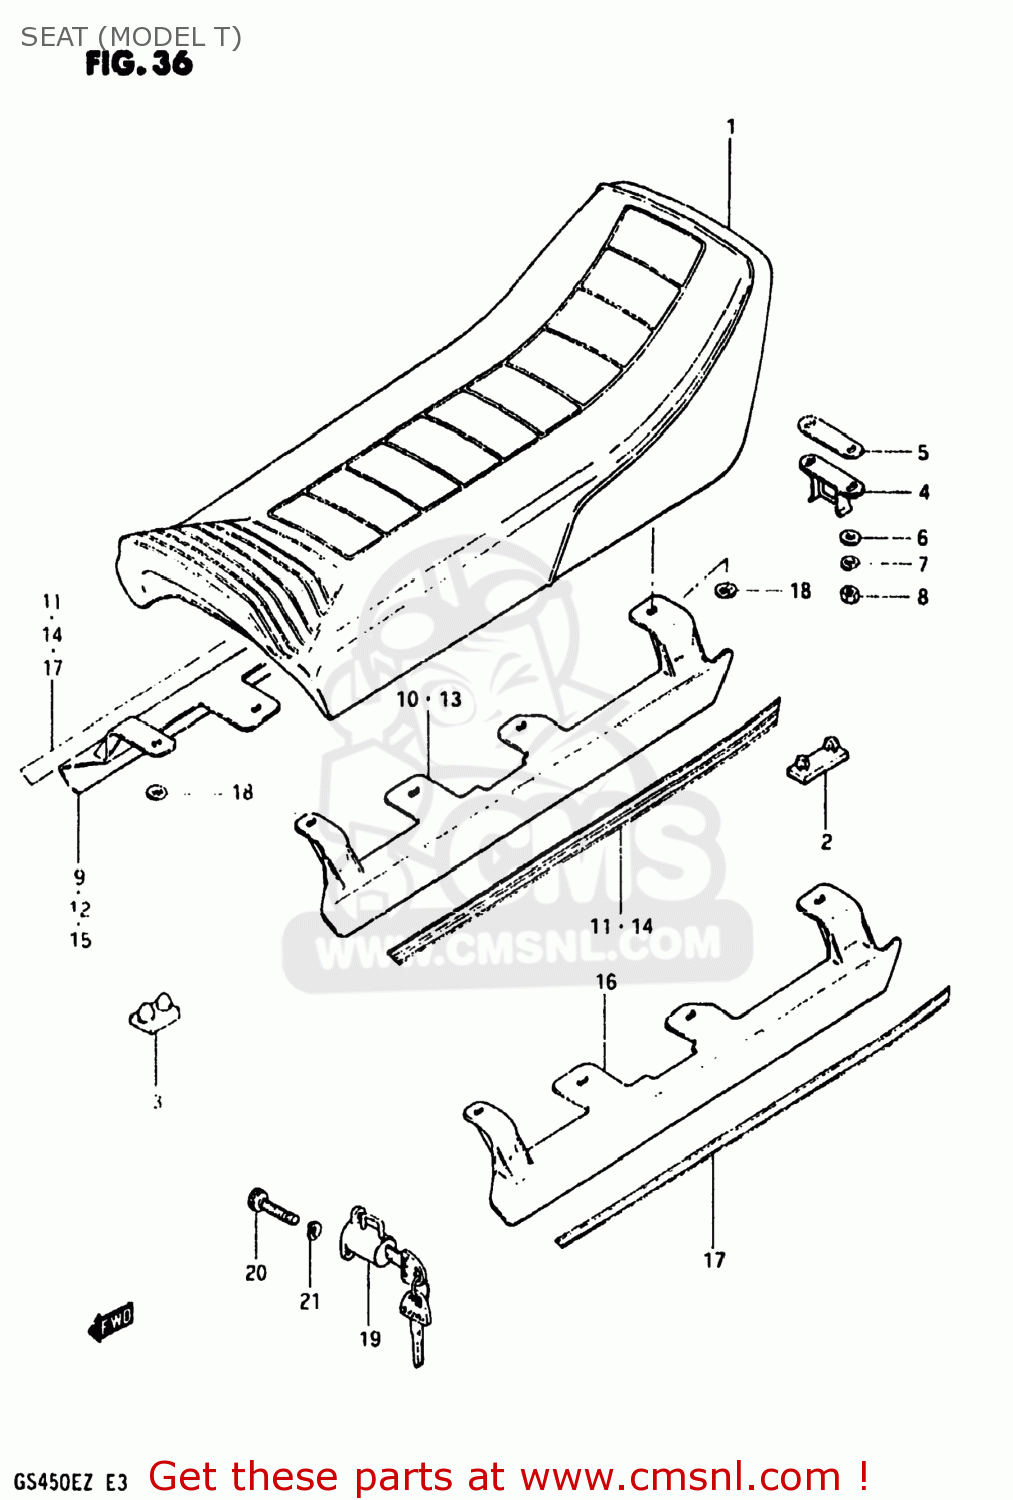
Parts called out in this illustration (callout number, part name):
1	SEAT ASSEMBLY
2	CUSHION
3	CUSHION
4	STRIKER,SEAT LOCK
5	SHIM,SEAT LOCK STRIKER
6	WASHER
7	LOCK WASHER
8	NUT 6MM
9	MOLDING,SEAT
10	MOLDING,SEAT
11	TAPE SET
12	MOLDING,SEAT
13	MOLDING,SEAT
14	TAPE SET
15	MOLDING,SEAT
16	MOLDING,SEAT
17	TAPE SET
18	NUT
19	LOCK ASSEMBLY,HELMET
20	BOLT 6X11
21	LOCK WASHER
